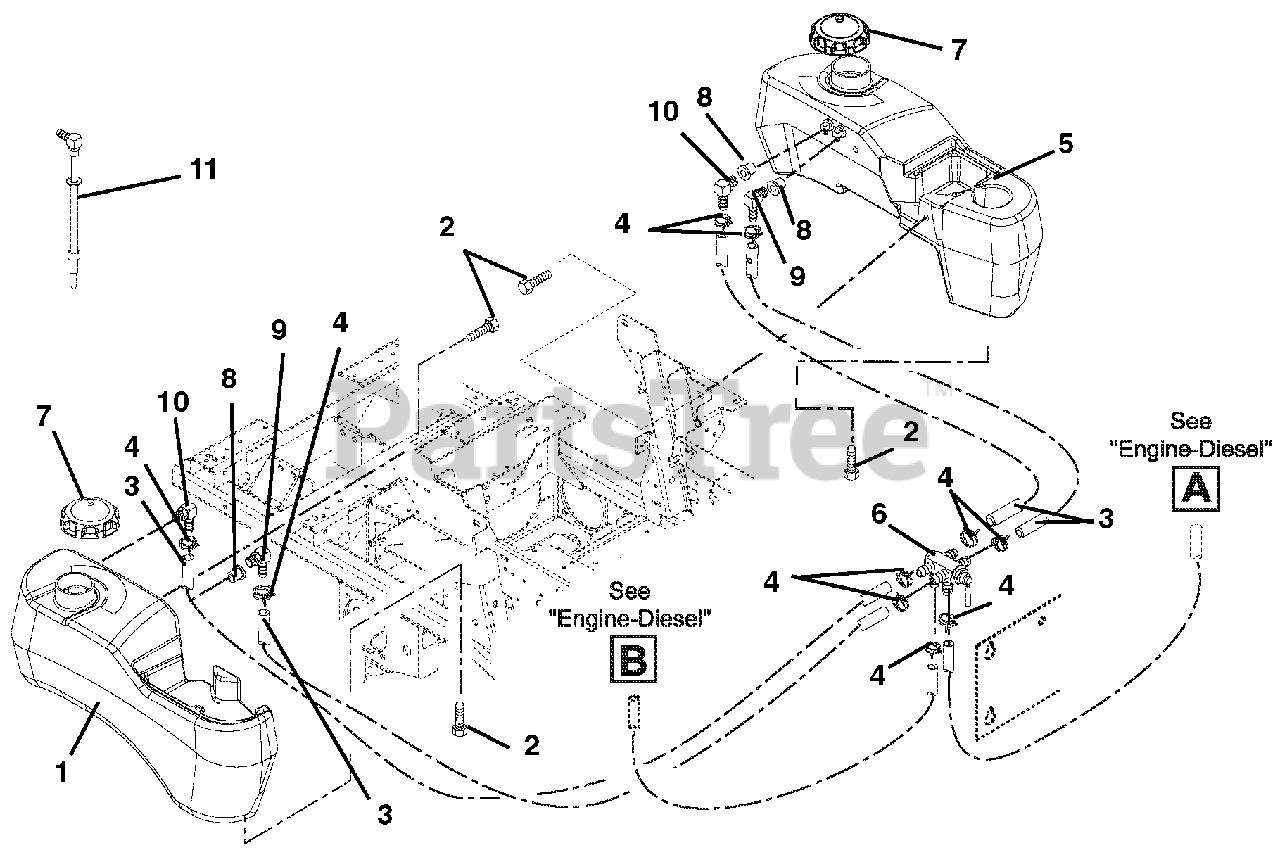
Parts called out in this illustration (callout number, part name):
1	Tank, Fuel-Right Hand
2	Bolt, SEMS .31-18 x .62
3	Hose, .31 ID
4	Clamp, Hose Wire .52/.55
5	Tank, Left Hand Fuel (EYE-Q) 200 Series-EFI
6	Valve, Fuel
7	Cap, Fuel
8	Grommet, Orange
9	Fitting, Tank
10	Fitting, Tank
11	26" Fuel Line Kit - Diesel (Inside Tank)
